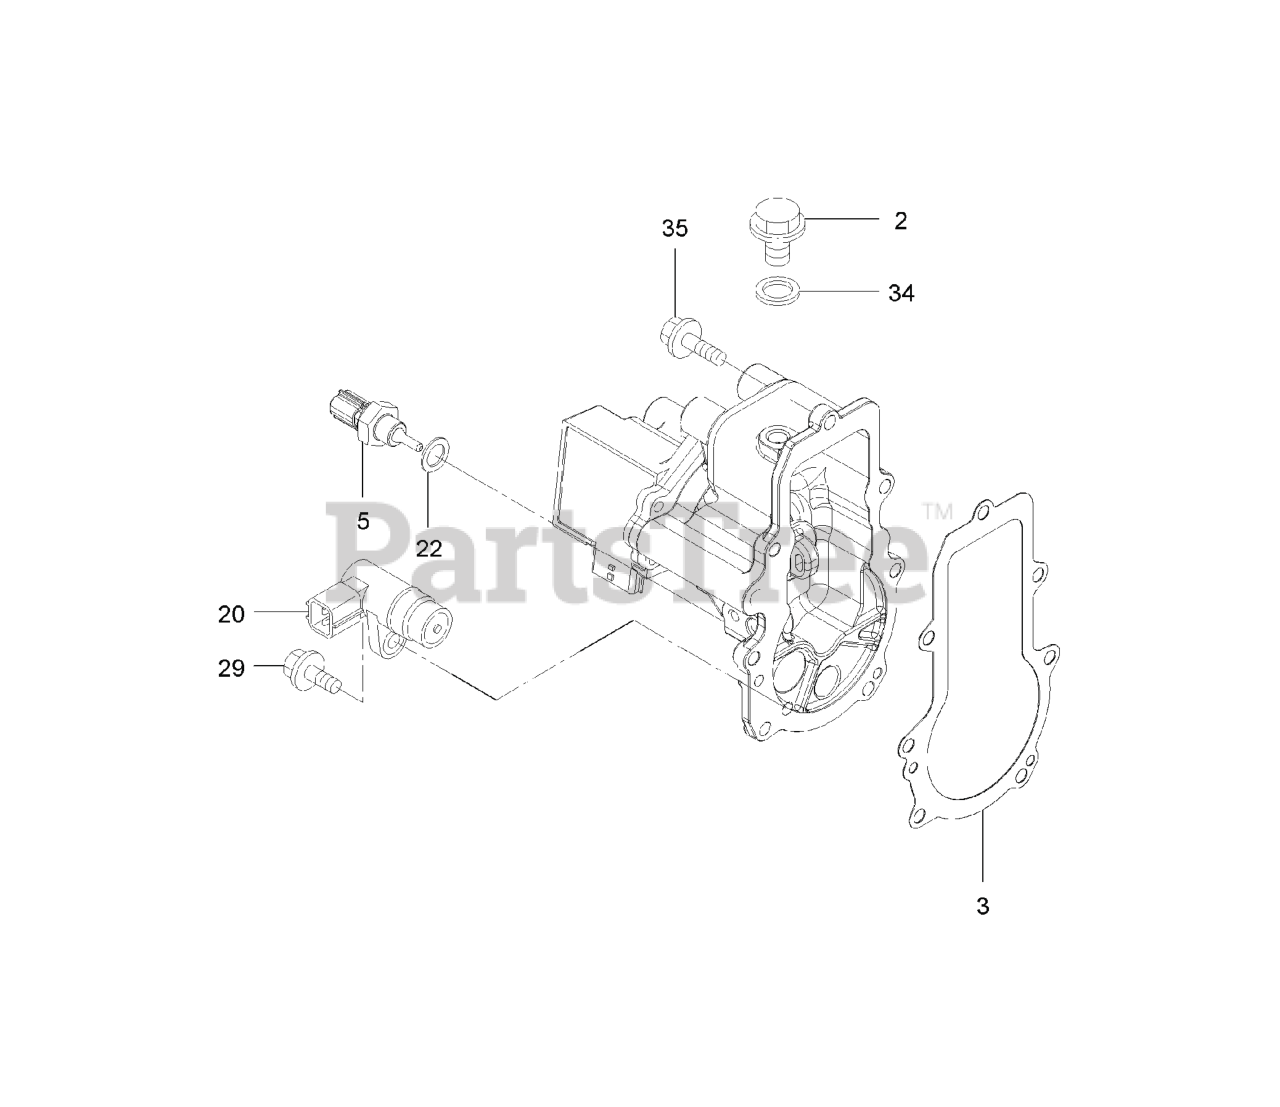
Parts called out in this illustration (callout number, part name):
5	SENSOR-OIL TEMP
22	WASHER-SEAL
34	WASHER-SEAL
